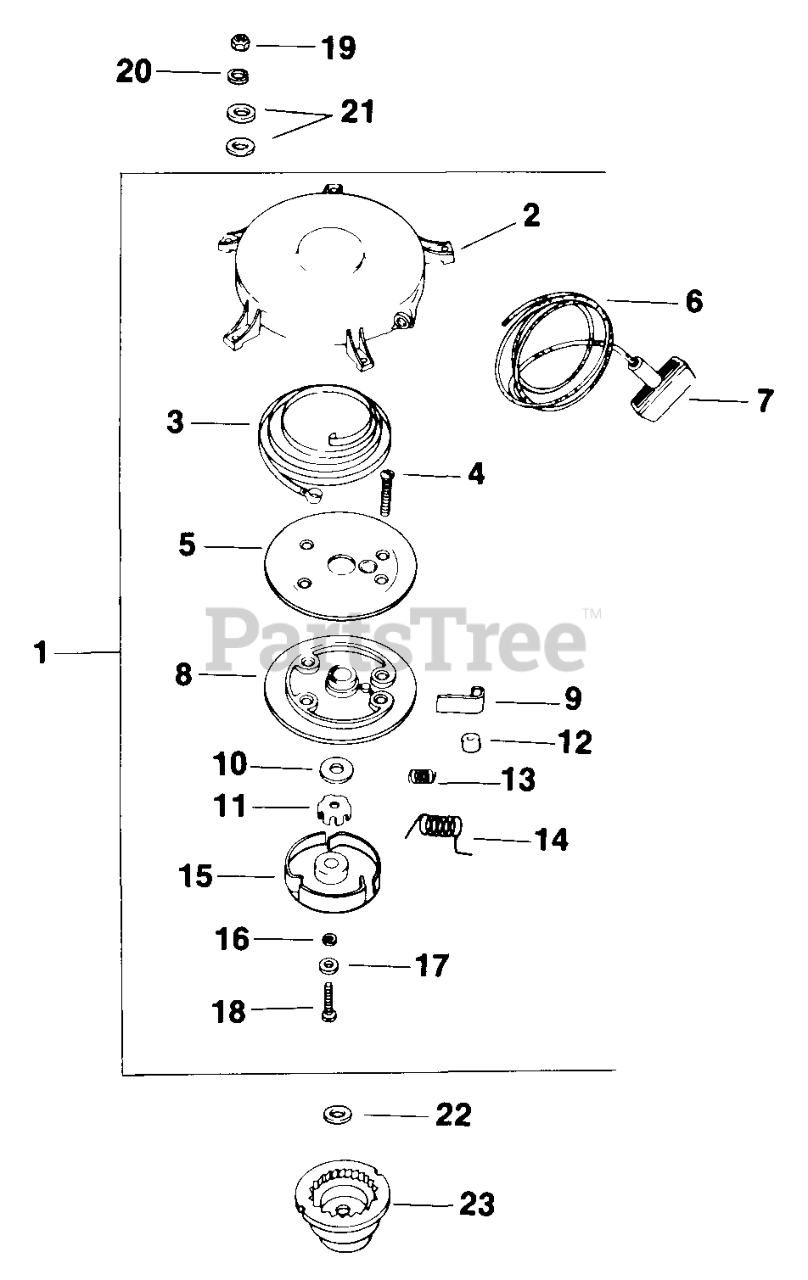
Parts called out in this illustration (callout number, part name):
1	STARTER
2	HOUSING - DISCONTINUED
7	HANDLE - USE 25 166 01
9	DOGS - DISCONTINUED
12	SPACER
13	SPRING - DISCONTINUED
14	SPRING
15	RETAINER
17	WASHER - DISCONTINUED
19	NUT, MACH SCREW #10-32 GRD 2 USE 25 100 18-S
20	WASHER, SPRING LOCK #10
22	WASHER (KM)-USE 12 468 03-S
23	CUP, DRIVE - DISCONTINUED
